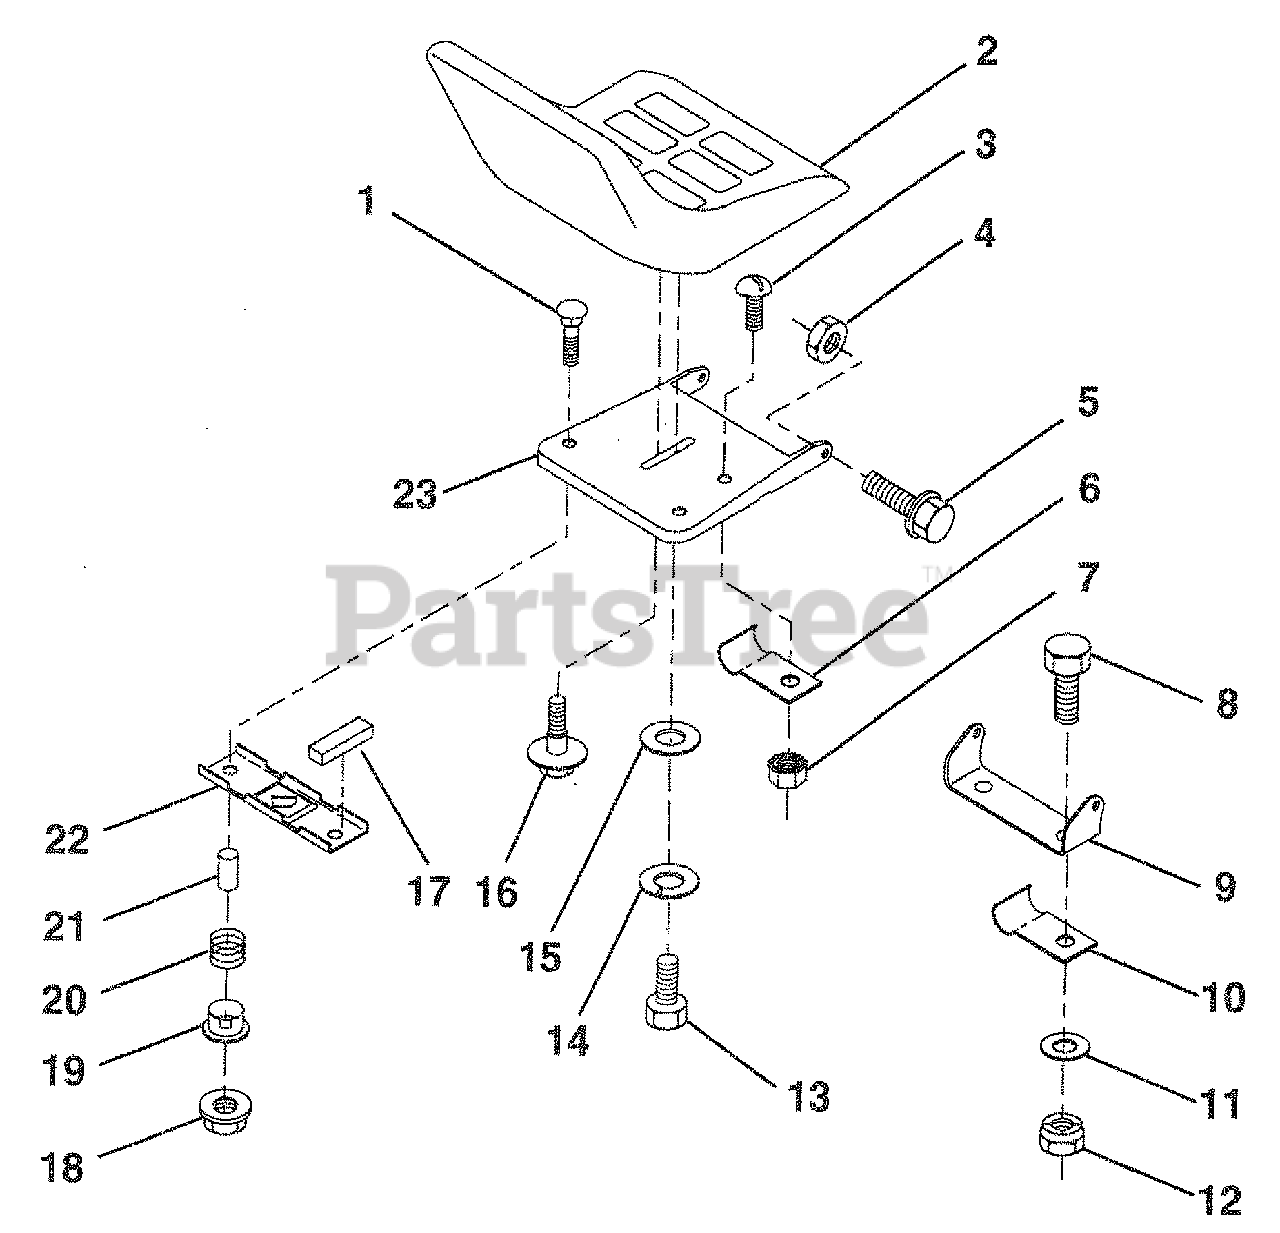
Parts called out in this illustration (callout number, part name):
1	Bolt, Carriage 1/4-20 x 1-3/8
2	Seat
3	Screw, Slotted Pan Head #10 - 32 x 1/2
4	Nut, Crownlock 5/16-18
5	Bolt, Shoulder 5/16 -18 UNC
6	Clip, Insulated
7	Nut, Keps #10-32 UNF
8	Bolt, Fin Hex 3/8 -16 UNC x 3/4
9	Bracket, Pivot Seat
10	Clip, insulated
11	Washer 12/32 x2 x 10 Ga.
12	Nut, Crownlock 3/8-16 UNC
13	Bolt, Fin Hex 1/2-13 x 7/8 Gr. 5
14	Washer, Lock Hvy H!c! Spr 1/2
15	Washer, 17/32 x 1 -3/16 x 12 Ga.
16	Bolt, Shoulder
17	Strip, Foam
18	Nut, Hex Large Flange Lock
19	Bushing, Snap
20	Spring, Compression
21	Spacer, Split 28 x .96
22	Bracket, Switch, Mounting
23	Pan, Seat
